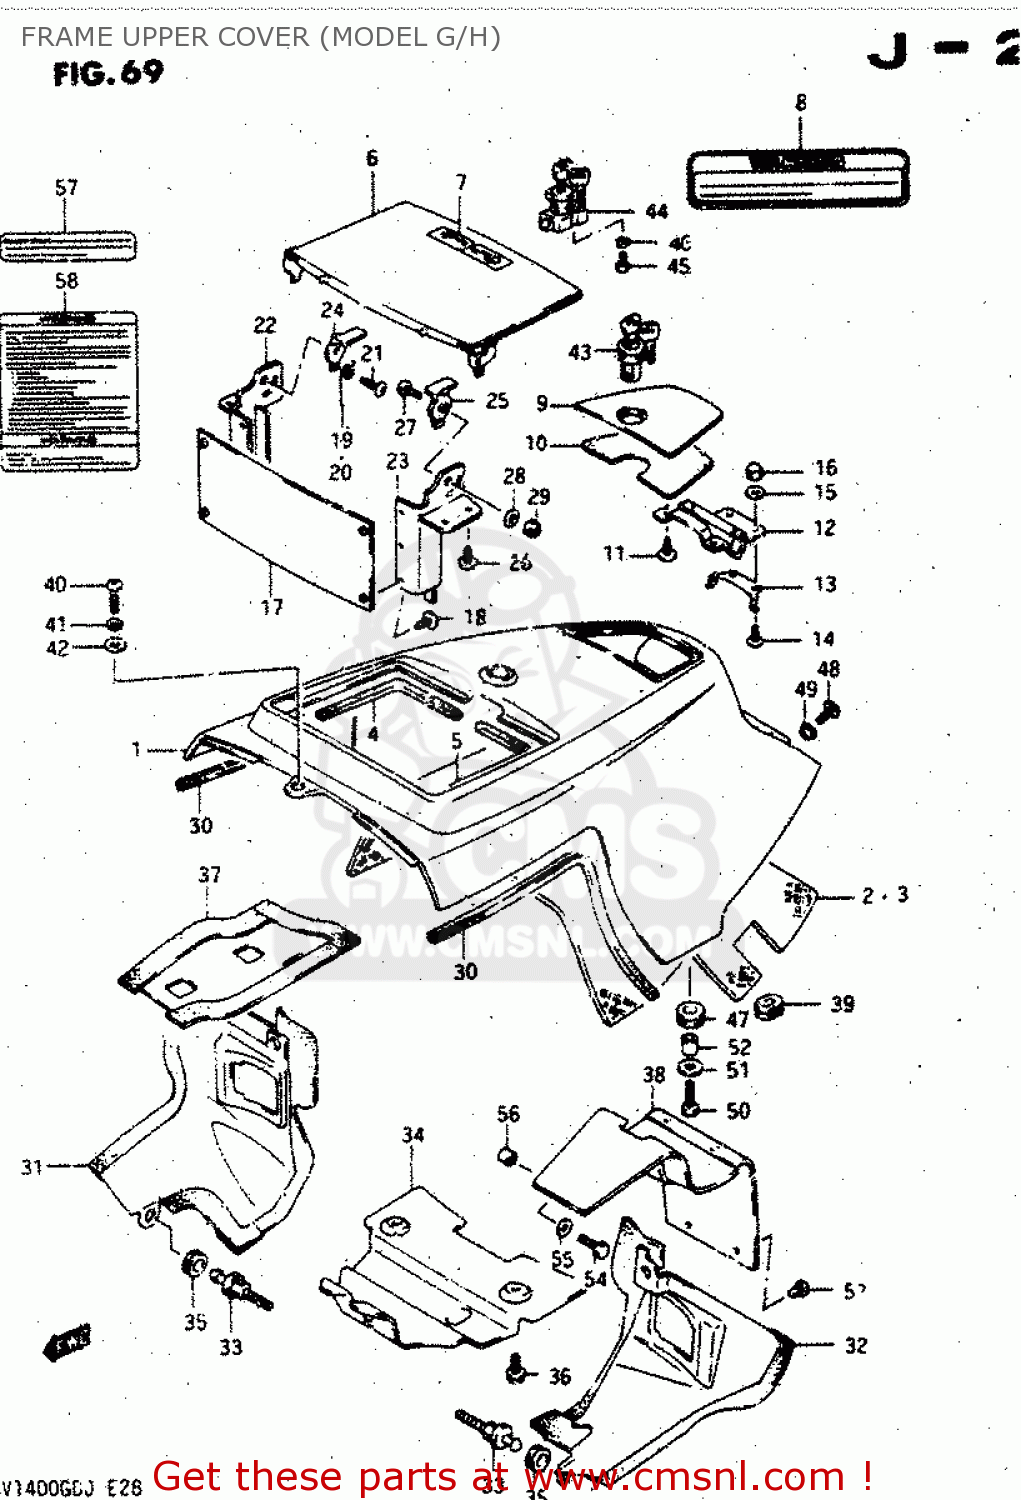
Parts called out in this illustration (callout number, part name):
1	COVER ASSEMBLY,FRAME,UPPER
2	CUSHION,FRAME COVER,UPPER
3	CUSHION,FRAME COVER,UPPER
4	CUSHION,AUDIO LID SIDE
5	CUSHION,AUDIO LID SIDE
6	LID SET,AUDIO
7	EMBLEM,AUDIO LID
8	LABEL, WARNING (FRENCH)
9	LID,FUEL
10	CUSHION,FUEL LID (NA)
11	SCREW 5X8
12	HINGE,FUEL LID
13	SPRING,FUEL LID HINGE
14	SCREW
15	WASHER
16	NUT
17	HOLDER,AUDIO LID
18	SCREW
19	SPRING
20	SPRING
21	SCREW
22	RAIL,RIGHT
23	RAIL,LEFT
24	RAIL PIECE,RIGHT
25	RAIL PIECE,LEFT
26	SCREW, RAIL
27	SCREW
28	WASHER
29	NUT 8MM
30	MOLDING,COVER FRAME,UPPER
31	COVER,INNER,RIGHT
32	COVER,INNER,LEFT
33	BOSS,FRAME COVER
34	COVER COMP,INNER
35	CUSHION
36	BOLT
38	COVER COMP,UPPER,LEFT
39	GROMMET
40	SCREW, 6X20
41	LOCK WASHER
42	WASHER (6.5X18X1.6)
43	LOCK SET,TOOL HOLDER
44	LOCK ASSEMBLY,AUDIO LID
45	SCREW
46	LOCK WASHER
47	CUSHION
48	SCREW
49	WASHER
50	BOLT
51	WASHER, LOWER
52	SPACER (6.1X8X9.5)
53	RIVET
54	BOLT
55	WASHER(6.5X16X1.2)
56	SPACER (6.5X12X8)
57	LABEL (WARNING AUDIO BO
58	LABEL, WARNING (FRENCH)
